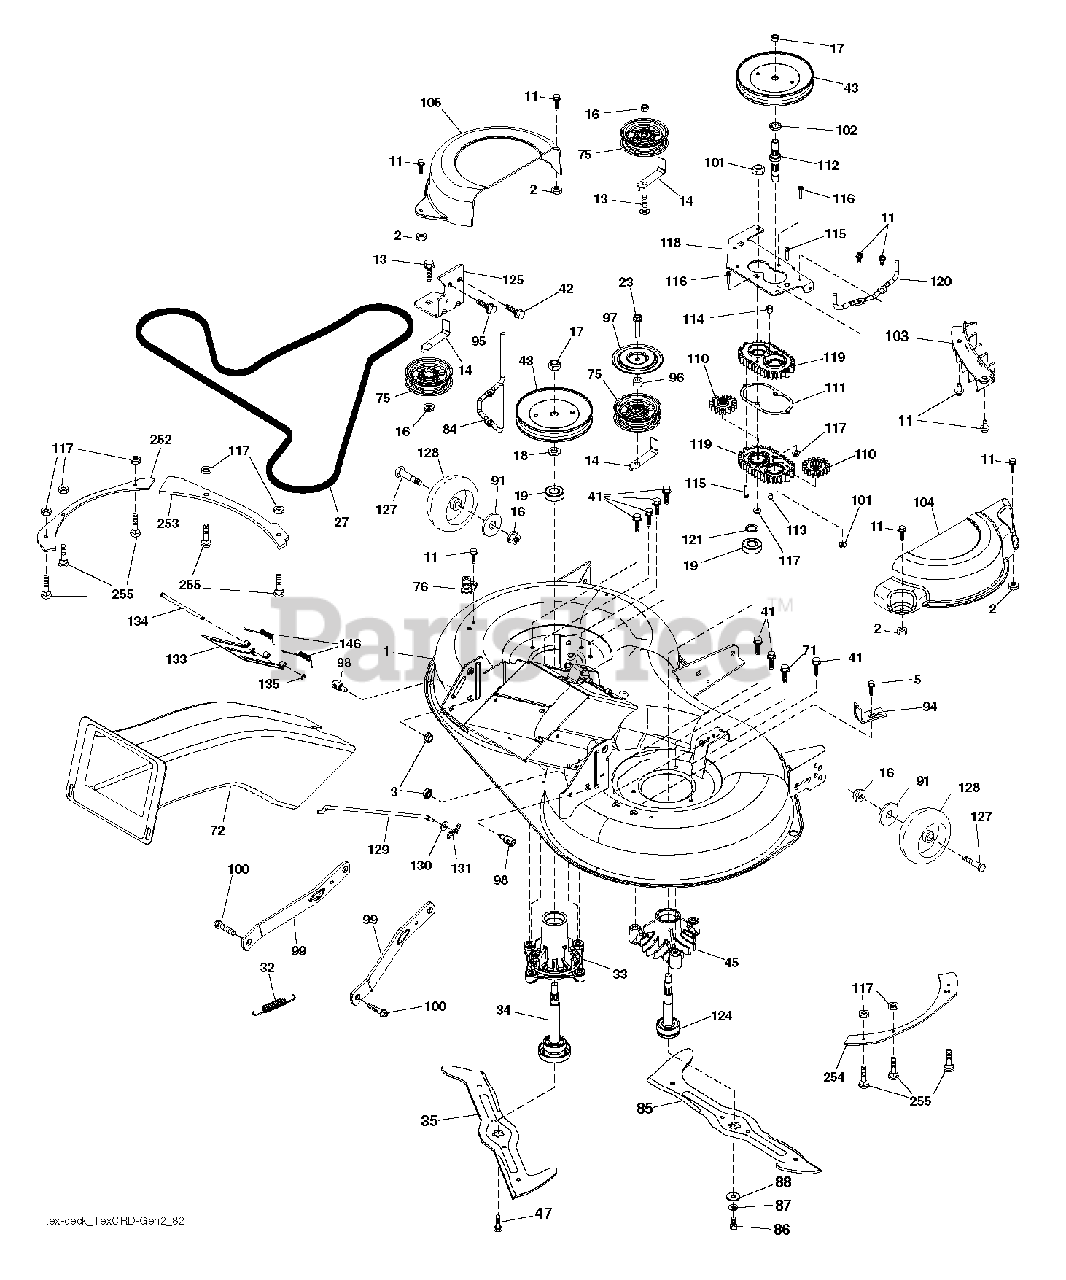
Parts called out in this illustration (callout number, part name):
1	DECK.SVC.WLDT.97EL.TCRD.EZ.498
2	PALNUT 1/4
3	NUT LOCK HEX FLANGE 5/16-18
5	BOLT.5/16HEX.WHS.HD
11	SCREW.1/4-20X5/8
13	BOLT.3/8-16X1.50
14	KEEPER, BELT IDLER
16	NUT LOCK FLG 3/8-16 UNC
17	NUT.FLANGE.LOCK.TOP
18	WASHER.SPACER.MANDREL
19	BEARING.MANDREL.TOP.EXTENDED
23	SCREW LT
27	BELT 97CM ELECTRIC
32	SPRING 107CM & 97CM ELECTRIC D
33	HOUSING.MANDREL.4PT.
34	SHAFT ASM.MNDRL.N/GREASEABLE
35	BLADE.3N1.LH.CRD.97
41	BOLT.HEX.WASHR.HED.313-18X1.19
42	SCREW
43	PULLEY.MANDREL.5.0.PD.38"
45	HOUSING.MANDREL.44/46" VENT
47	SCREW.SEMS.7/16-20X1.HEX.HEAD
71	SCREW 3/8-16X1/2
72	RB CHUTE 107/97 TEX GENII
75	FLAT IDLER PULLEY
76	PORT.WASHOUT
84	BELT KEEPER.MANDREL.38"COATED
85	BLADE.3N1.RH.CRD.97
86	BOLT.3/8-24X1.25GR8. LHTHRD
87	LOCKWASHER
88	WASHER.BLADE
91	WASHER
94	BRKT.CLUTCH.CABLE
95	SCREW, 3/8-16X3/4
96	SPACER
97	PROTECTOR
98	STUD.FASTNER.W/ANTI-ROTATE
99	ARM.SUSPENSION.MOWER.R
100	BOLT.SHOULDER
101	NUT.CROWNLOCK.9/16 -18.UNC
102	SPACER BEARING
103	GUARD GUARD FRONT VENT
104	97.CRD.RH.MANDREL.COVER
105	MANDREL MANDREL COVER LH
110	CRD.SPUR.GEAR
111	GASKET GASKET GEARCASE
112	SHAFT SHAFT. CRD GEARCASE ADAP
113	PLUG PLUG OIL
114	VENT.BREATHER.1/8 NPT
115	SCREW
116	BOLT.CARIGE.SS.1/4-20X1.75GR5
117	NUT T
118	ARM ARM CLUTCHING
119	GEARCASE GEARCASE SUBASM
120	BRACKET KEEPER BELT RH
121	WASHER WASHER
124	MANDREL SHAFT NON/GREASE
125	BRACKET
127	BOLT.SHOULDER.3/8-16X3-5/8.
128	WHEEL. GUAGE RALLY
129	ROD ROD. SWAY CRD GEN II
130	WASHER
131	PIN.COTTER.5/16.BOW TI
133	DOOR
134	PIN PIN.HINGE
135	E-RING.5/16"
146	SPRING SPRING: EZ MULCH DOOR
252	PLATE.REINFORCEMENT.X431
253	PLATE.REINFORCEMENT.LHS.X431
254	PLATE.REINFORCEMENT.LHS.X431
255	RHSNB, 1/4-20 X 1, GR5
